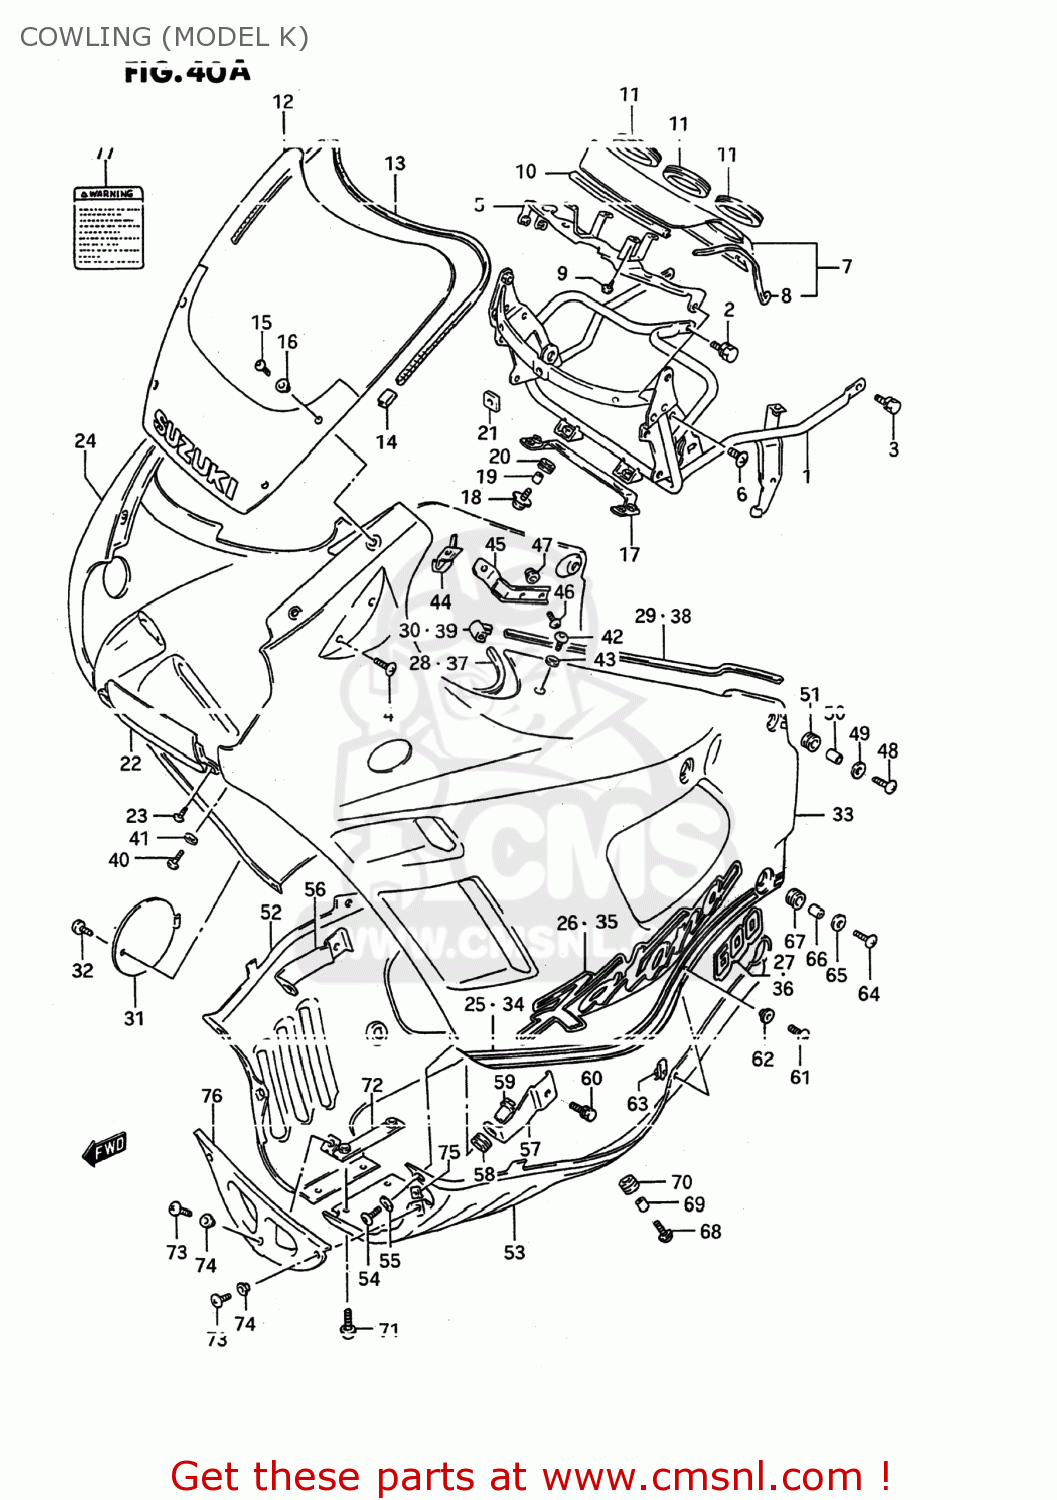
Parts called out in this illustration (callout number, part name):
1	BRACE,COWLING
2	BOLT
3	BOLT 6X12
4	SCREW 6X12
5	PLATE,METER FITING
6	SCREW 6X12
7	COVER,METER
8	MOLDING
9	SCREW 5X8
10	MOLDING,METER COVER
11	CUSHION,METER COVER
12	WINDOW,COWLING
13	MOLDING
14	CAP,MOLDING END
15	SCREW
16	WASHER(5.2X11X1)
17	PLATE,COWL CTR PANEL
18	SCREW(6X20)
19	SPACER (6,8X10X9.4)
20	CUSHION
21	CUSHION,SCREEN
22	PANEL,COWLING,CENTER
23	SCREW
24	KUIPDEEL. RH
25	TAPE SET,RH
26	EMBLEM
27	EMBLEM (600)
28	MOLDING
29	MOLDING
30	JOINT,MOLDING END
31	LID,OIL
32	SCREW(6X16)
33	KUIPDEEL. LH.
34	TAPE SET,COWL,L
35	EMBLEM
36	EMBLEM (600)
37	MOLDING
38	MOLDING
39	JOINT,MOLDING END
40	SCREW(6X25)
41	WASHER(6.5X18X1.5)
42	SCREW(6X16)
43	WASHER(6.3X16X1.5)
44	BRACKET,COWLING UPR,R
45	BRACKET,COWLING UPR,L
46	SCREW(6X25)
47	NUT,COWLING SIDE BRKT
48	SCREW(6X25)
49	WASHER(6.5X18X1.5)
50	SPACER (6.1X9X9)
51	CUSHION
52	COVER COWLING
53	COVER COWLING
54	SCREW(6X30)
55	WASHER(6.5X18X1.5)
56	BRACKET,COWLING LWR,R
57	BRACKET,COWLING LWR,L
58	CUSHION
59	NUT,COWLING,FR
60	BOLT
61	SCREW(5X14)
62	WASHER(5.2X14X1.5)
63	NUT,HEADLAMP HOUSING,UPPER
64	SCREW(6X25)
65	WASHER(6.5X18X1.5)
66	SPACER(6.1X9X12.3)
67	CUSHION
68	SCREW(6X20)
69	SPACER (6.1X9X9)
70	CUSHION
71	SCREW, LOWER
72	BRACKET,FR UNDER COWL
73	SCREW
74	WASHER(5.2X14X1.5)
75	NUT,HEADLAMP HOUSING,UPPER
76	COVER,COWLING UNDER FR
77	LABEL (WARNING SCREEN)
